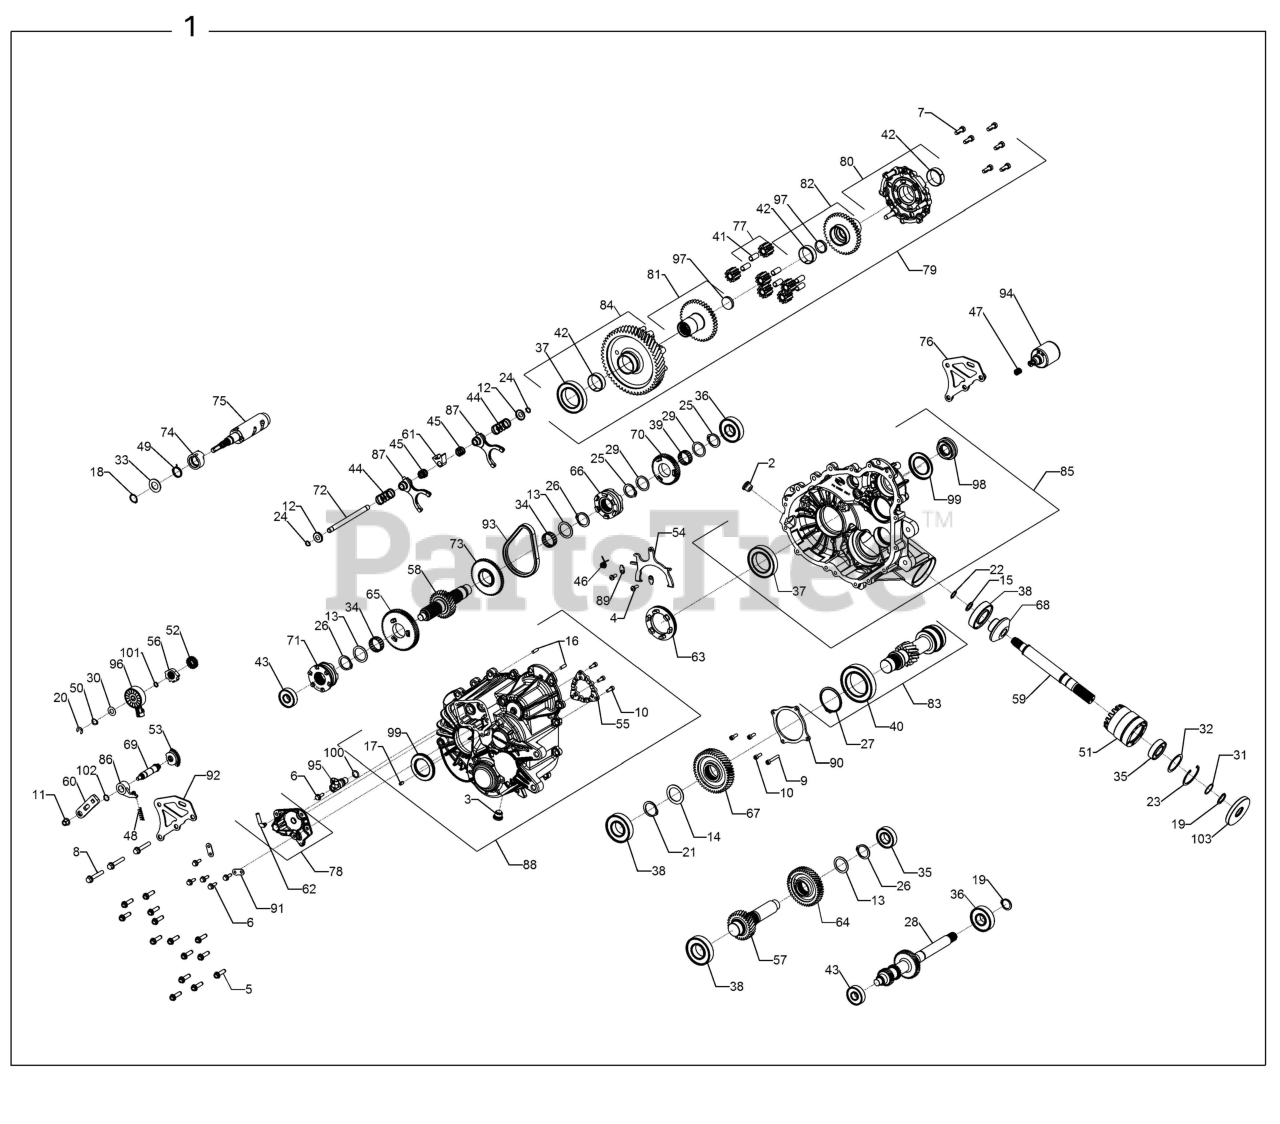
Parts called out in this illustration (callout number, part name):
1	ASM-GEARCASE,DIESEL,RGR
2	PLUG-SKT HD 1SO 6149,M18 X 1.5
3	PLUG-SOCKET HEAD W/MAG,M18X1.5
4	SCREW, TORX PAN HD M6 X 1 X 16
5	SCREW-HEXFLANGEHEAD,M8X1.25X30
7	SCREW-CAP HH,M8 X 1.25 X 20
9	SCR-M6X1.0X40,SOC/CAP(105344)
10	SCR-SCKT HD,CP,M6X1X18(105355)
11	NUT-M8X1.25,HXFLG,NYLN(110093)
12	WASHER-CUP
16	PIN, DOWEL, 6 X 20
17	SPRING-SLOTTED PIN,6MM
18	RING, RETAINING BASIC EXTERNAL
19	RING, SNAP
20	RING-RETAINING
21	RING,RETAINING
22	RING,RETAINING,EXTERNAL SHR-66
23	RING,RETAININGBASICINTRNL2.047
24	RING-RETAINING
25	RING,RETAINING
26	RING, RETAINING, EXTERNAL
27	RING, RETAINING
28	SHAFT, INPUT, HELICAL
29	WASHER,THRUST
30	WASHER,THRUST,.446X.88X.025
31	SHIM 1.180 X .995
32	SHIM 2.040 OD X 1.630 ID
33	SPACER, 19.4 X 34 X 2
34	BEARING,NEEDLE
37	BEARING, BALL
38	BEARING-BALL
39	BEARING,NEEDLE
40	BEARING, BALL
41	SCREW, TORX PAN HD M6 X 1 X 16
42	PLAIN,BEARING 40X44X15
43	BEARING, BALL
44	SPRING-COMPRESSION
45	SPRING-COMPRESSION
46	SPRING, TORSION RETURN
47	SPRING,COMPRSSN.54ODX.44IDX.05
48	SPRING, COMPRESSION DETENT
49	SPRING, TORSION
50	WASHER-SPRING,210393
51	TUBE, SNORKLE MACH
52	GEAR-SECTOR,16T
53	GEAR-SECTOR,31T-CUT TO 11T
54	SHIFT FORK (270507)
55	PARK PLATE (270509)
56	STAR, DETENT
57	SHAFT, IDLER, 29T
58	SHAFT, REVERSE, 29T
59	SHAFT, OUTPUT, FRONT
60	BELLCRANK
61	COLLAR-SHIFT
62	TUBE-VENT,90-1/4" HOSE
63	DOG-ENGAGEMENT
64	GEAR, 44T, STAGE 2
65	GEAR-LOW,67T(352856)
66	DOG, ENGAGEMENT, 6-FACE
67	GEAR, 46T, STAGE 3
68	GEAR-13T,FRONT OUTPUT(352957)
69	SHAFT, SHIFT
70	GEAR 49T
71	SHIFT DOG, PARK/LOW (353357)
72	RAIL-SHIFT SHAFT(353622)
73	SPROCKET, 48T, 6-FACE
74	PARK CAM
75	DRUM, SHIFT MACH
76	WELD-REAR MOUNT BRKT
77	GEAR SUBASSEMBLY
78	SUBASSY COVER, SECTOR GEARS
79	DIFF-LOCKING (411600)
80	SUBASSY-COVER,DIFF (411601)
81	SUBASSY-GEAR,39T SIDE (411607)
82	SUBASSY-GEAR,39T SIDE (411608)
83	ASM-SUB,PINION SHAFT(411759)
84	SUBASSY-GEAR,53T (411797)
85	SUBASSY,LH CASE(411919)
86	ROLLER PAWL
87	SUBASSEMBLY, SHIFT FORK
88	SUBASSEMBLY RH COVER
89	RETAINER-FORK
90	COVER, BEARING, CENTER DRIVE
91	BRKT-MOUNT(430592)
92	BRKT-REAR MOUNT
93	CHAIN, SILENT
94	SOLENOID
95	SENSOR-SPEED,TRANS
96	SWITCH, ROTARY 2 PIN RESISTIVE
97	PLUG,EXPANSION,1 1/4
99	SEAL-TRIPLE LIP,VITON,40X70X7
100	O-RING, -113
103	SEAL-TRIPLE LIP 25X80X10
